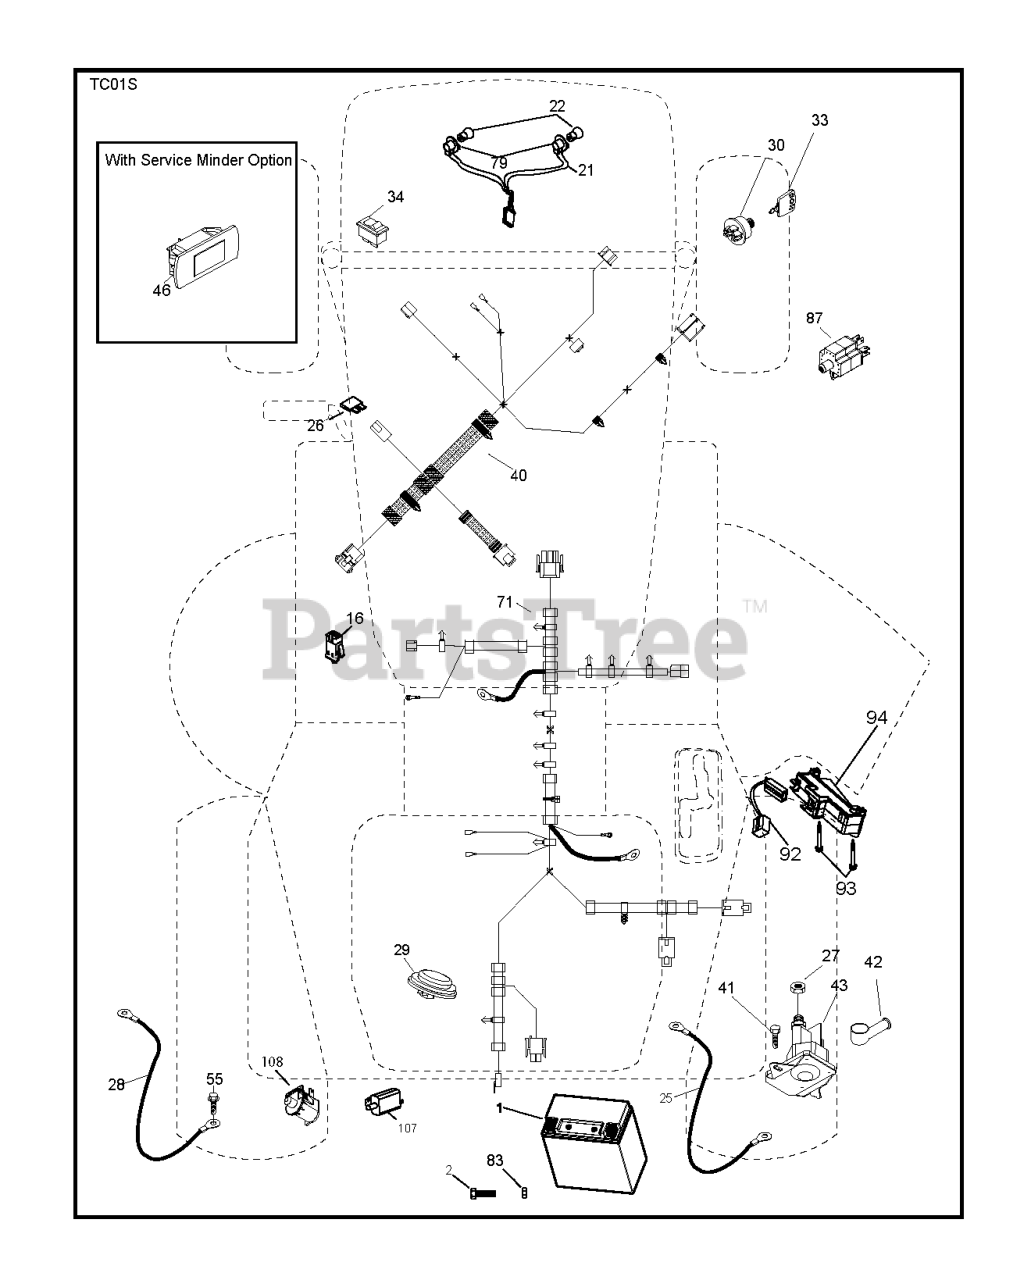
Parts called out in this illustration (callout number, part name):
1	BATTERY BATTERY 14AH 12V LEOC
2	SCREW.HEX.HEAD.CAP.M6 X1.12W
16	SWITCH INTERLOOK PUSH-IN
21	HARNESS.LIGHT W/4152J BULBS
25	RP.CABLE BATTERY CABLE
26	FUSE 20AMP
27	NUT
29	SWITCH.SEAT.DELTA.OPC.
30	SWITCH.IGN.DELTA.W.LGH.ROS
33	KEY.CHAIN.BLISTER.PACK.GEN.INT
40	RP HARNESS.ELECTRICAL.DASH.SRD
41	SCREW
42	TERMINAL COVER
43	SOLENOID.W/BRASS.PLUNGER
55	SCREW 5/16"
79	BULB HOLDER ASM.
83	NUT NUT SQUARE
87	RP SWITCH.RAILMOUNT.NO-NC-NC
92	HARNESS.PIGTAIL.CONSLE
93	SCREW.PLASTITE
94	MODULE.REVERSE.ROS
107	.WITCH.FULL BAGGER.INDICATOR
108	SWITCH.SNAPMOUNT.NC
